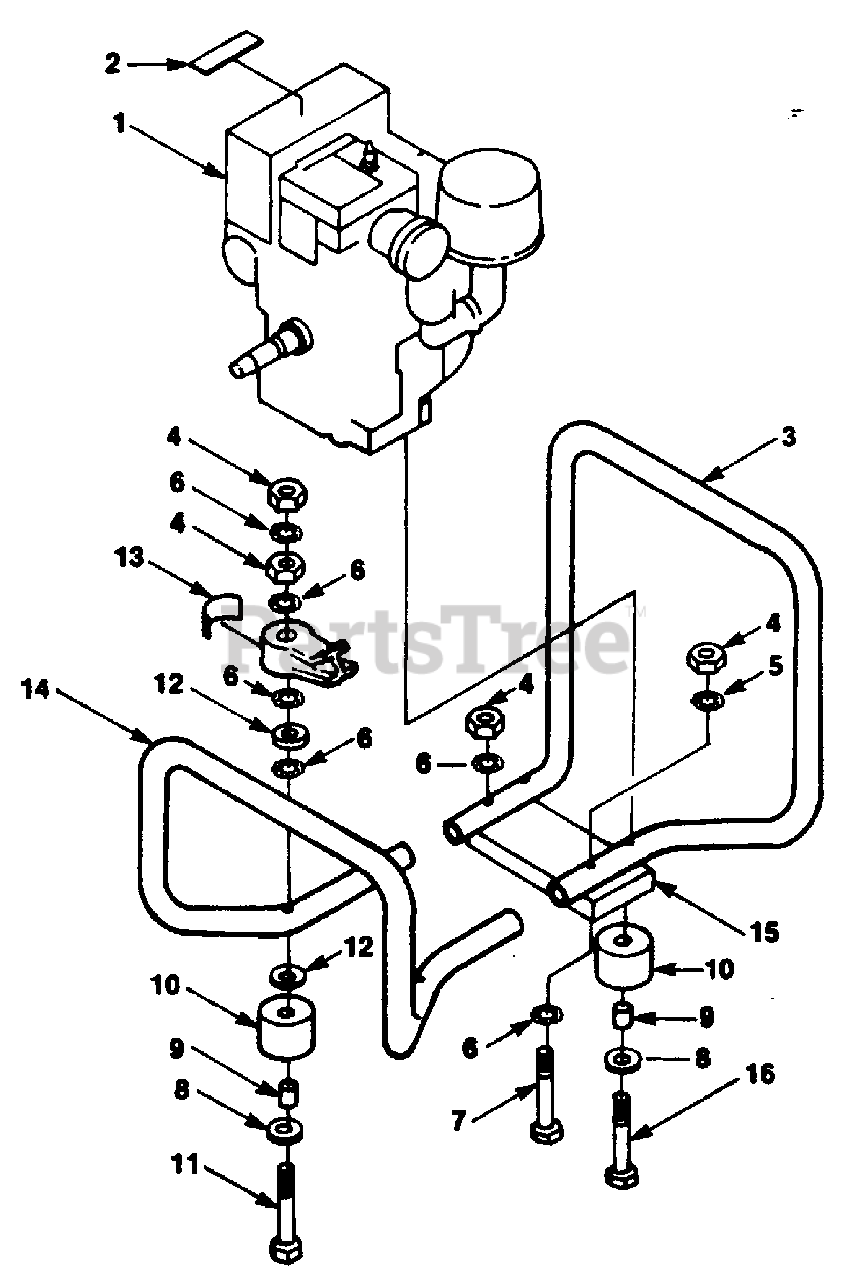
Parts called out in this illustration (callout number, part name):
2	DECAL- Warning
3	MEMBER- Frame (engine)
4	NUT- Hex (5/16-18)
5	WASHER- Lock int. (5/16")
6	WASHER- Lock ext./int.
7	BOLT- Engine (rear)
8	WASHER- Flat (5/16")
9	SPACER- Foot
11	SCREW- Cap hex. hd. (5/16-18 x 3")
12	WASHER- Flat (5/16")
13	DECAL- Ground
14	FRAME- Member (generator)
15	PLATE- Frame
16	BOLT- Engine (front)
